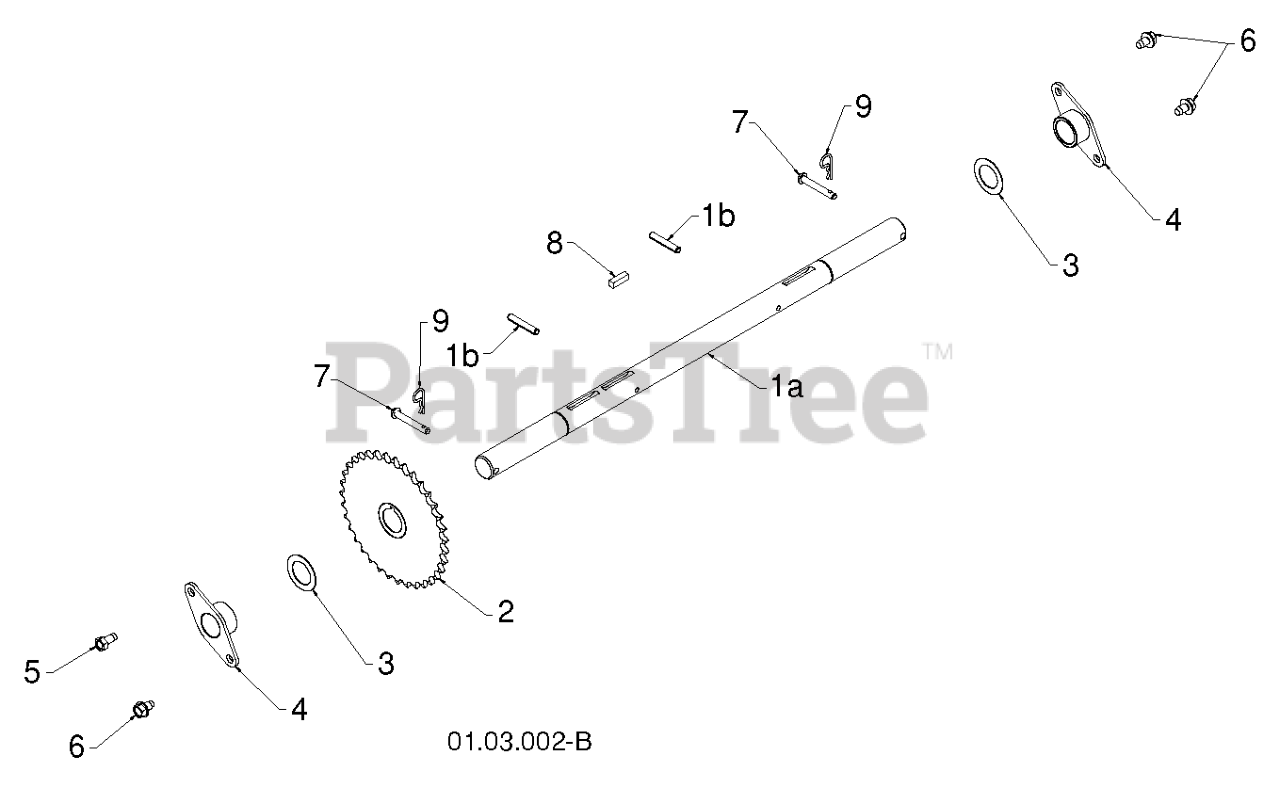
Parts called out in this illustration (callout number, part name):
1	AXLE.ASM.SHAFT.W/ROLLPIN.PS
1A	SHAFT.AXLE.POWER.STEERING
1B	PIN.ROLL.3/16
2	SPROCKET.WELDMENT.AXLE.1.00
3	WASHER TRUST 1"
4	BEARING, AXLE
6	SCREW LT
7	RIVET
8	KEY, SQUARE 1/4 X .875
9	RETAINER M
